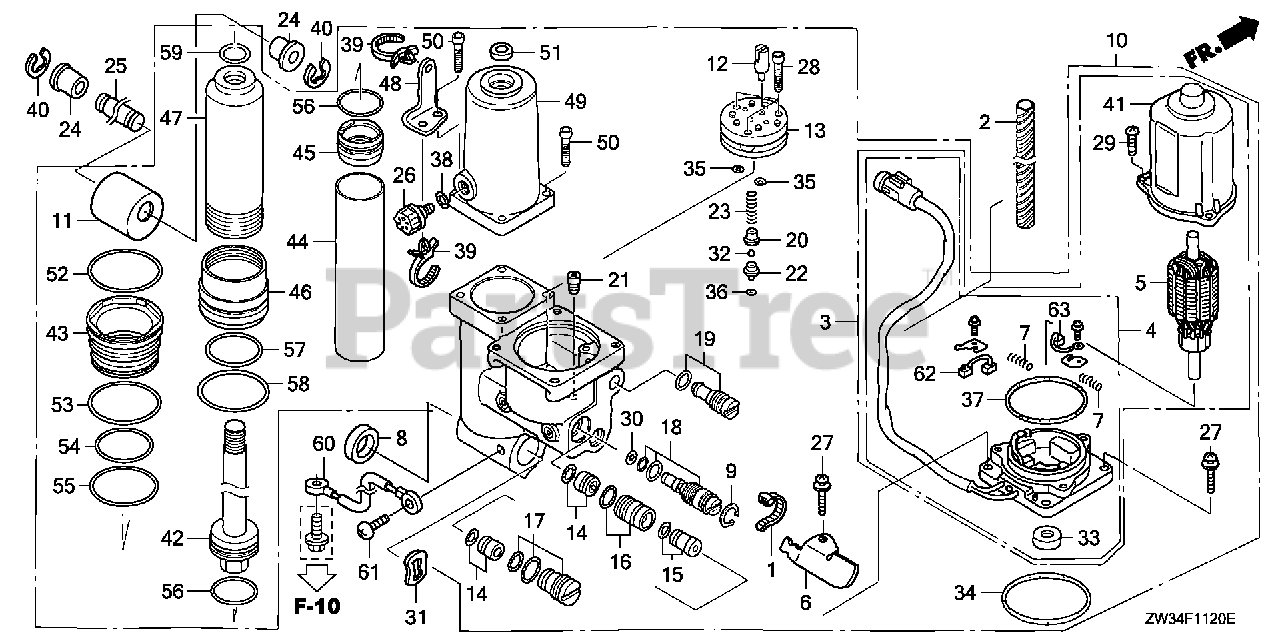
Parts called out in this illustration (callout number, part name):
1	BAND (BLACK 3.5X140)
2	TUBE, SPIRAL
3	MOTOR ASSY., POWER TILT
4	BRACKET ASSY.
6	CLAMP, WIRE
7	SPRING, MOTOR
8	SPACER (19.4X6)
9	CIRCLIP (INNER) (16)
10	TRIM-TILT ASSY., POWER
11	METAL, JOINT
12	JOINT, DRIVE
18	VALVE, MANUAL
20	GUIDE, SPRING
21	VALVE, SET
22	SEAT B, VALVE
23	SPRING, VALVE
24	BUSH, CYLINDER (UPPER)
25	PIN, CYLINDER (UPPER)
26	CAP, OIL TANK
27	SCREW-WASHER
28	BOLT, SOCKET
29	SCREW, PAN (5X20)
30	WASHER, SEAL
31	WASHER, WAVE (26MM)
32	BALL, STEEL
34	O-RING (1.8X69.6)
35	O-RING (1.5X6.5)
36	O-RING (1.5X3.5)
37	O-RING (2.0X55.5)
38	O-RING (1.8X10.8)
39	CLIP, HARNESS BAND (145MM) (BLACK)
40	E-RING (10MM)
42	ROD, PISTON
43	GUIDE, TUBE (OUTER)
45	PISTON, FREE
46	LOWER TILT CYLINDER
47	TUBE (OUTER)
48	PLATE, SET
50	BOLT, SOCKET (5X0.8)
51	SEAL, WATER
52	O-RING (2.0X52.5)
53	O-RING (2.0X49.5)
54	O-RING (2.4X41.2)
55	O-RING (2.0X45.5)
56	O-RING (2.0X28.5)
57	O-RING (2.0X34.5)
58	O-RING (3.5X41.7)
59	O-RING (2.4X15.8)
62	BREAKER ASSY.
63	BRUSH ASSY.
